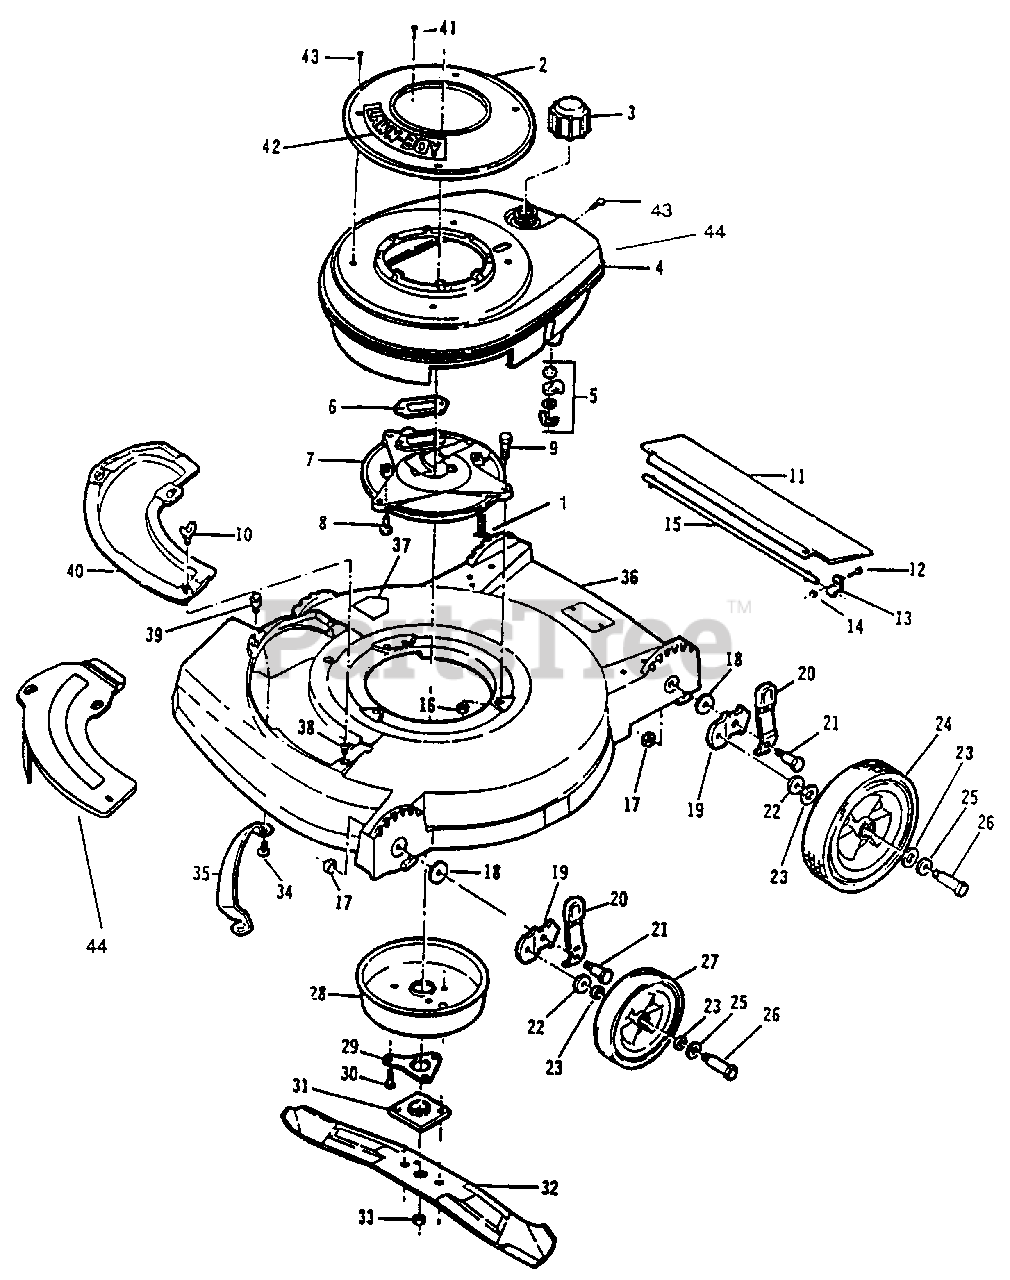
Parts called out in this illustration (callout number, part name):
1	Screw
2	Starter Base
3	Fuel Cap
4	Shroud-Engine (Inc. 5)
5	Fuel Shut-Off Assembly
6	Gasket-Exhaust
7	Plate-Muffler
8	Screw-Muffler Plt. to Block
9	Screw-Muffler Plt. to Hsg.
10	Wing Screw
11	Shield-Trailing
12	Screw-Trailing Shield
13	Clamp
14	Nut
15	Rod-Trailing Shield
16	Nut-Muffler Plt. to Hsg.
17	Nut-Wheel Ht. Adjust
18	Washer-Wheel Ht. Adjust
19	Bracket-Wheel Ht. Adjust
20	Knob & Spring Assembly
21	Bolt-Shoulder
22	Washer
23	Washer-Felt
24	Wheel-Rear
25	Washer-Wheel Bolt
26	Bolt-Wheel
27	Wheel-Front
28	Muffler Cover Assembly
29	Support-Crankshaft
30	Screw-Muff. to Muff. Plate
31	Collar & Plate Assembly
32	Blade 19"
33	Nut
34	Screw
35	Toe Bar
36	Housing Assembly (Inc. 37-38)
37	Decal-Blade Contact Warning
38	Grommet
39	Screw-Plate Mounting
40	Cover Plate
41	Screw-Starter Mounting
42	Applique
43	Screw-Shroud
44	Mulch Plate Accessory
45	Decal-Fuel Mix
